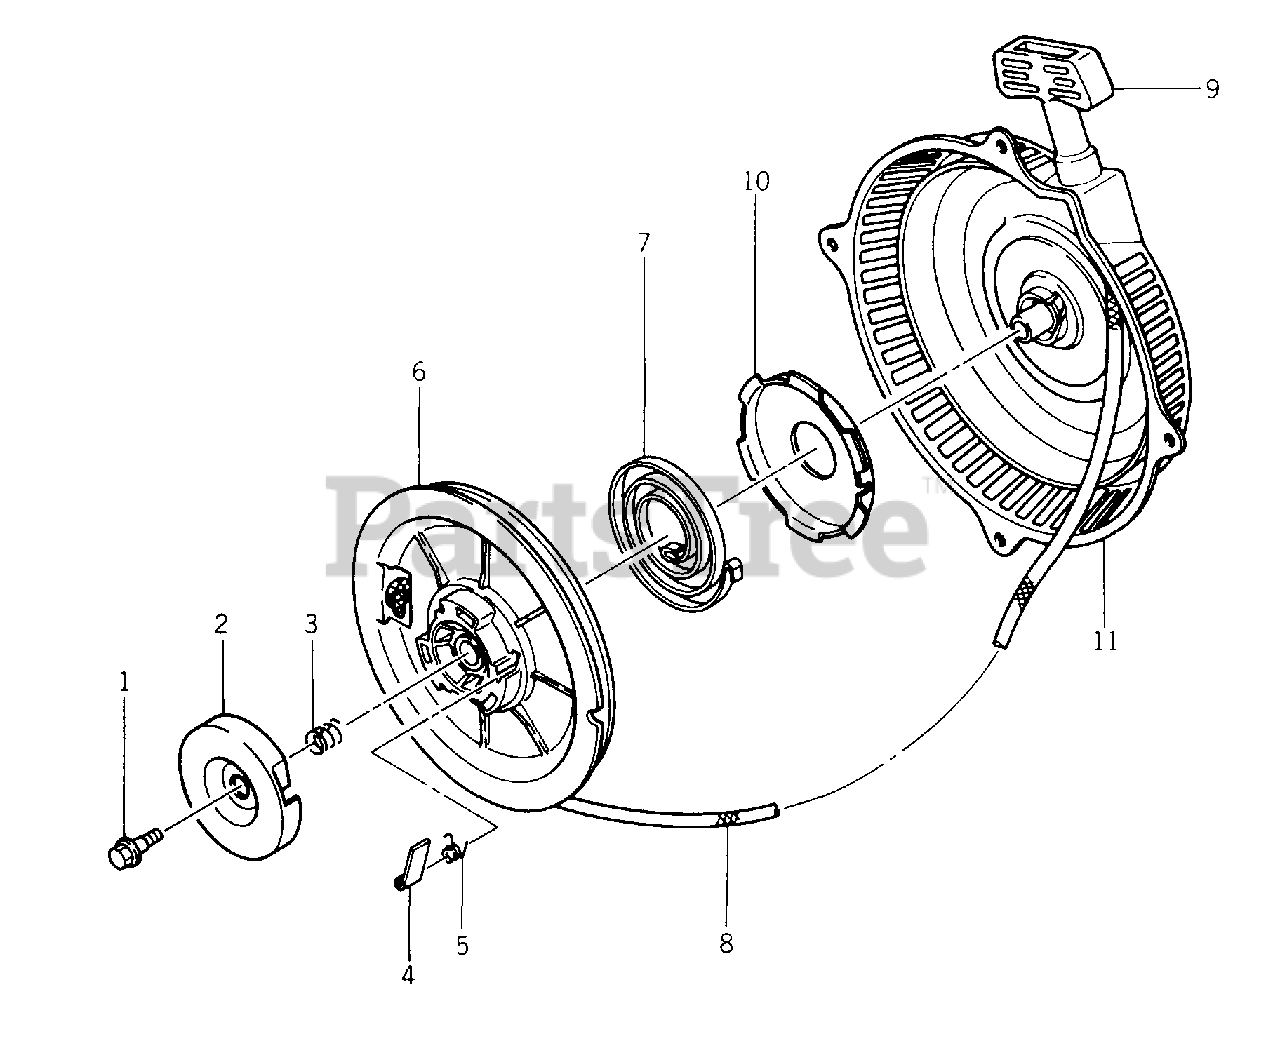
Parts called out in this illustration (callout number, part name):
1	BOLT
3	SPRING, return
4	PAWL
5	SPRING, return
6	REEL, recoil
7	SPRING, recoil
8	EUROPE (6x1380)
9	GRIP
10	CASE, spring
11	CASE, recoil
